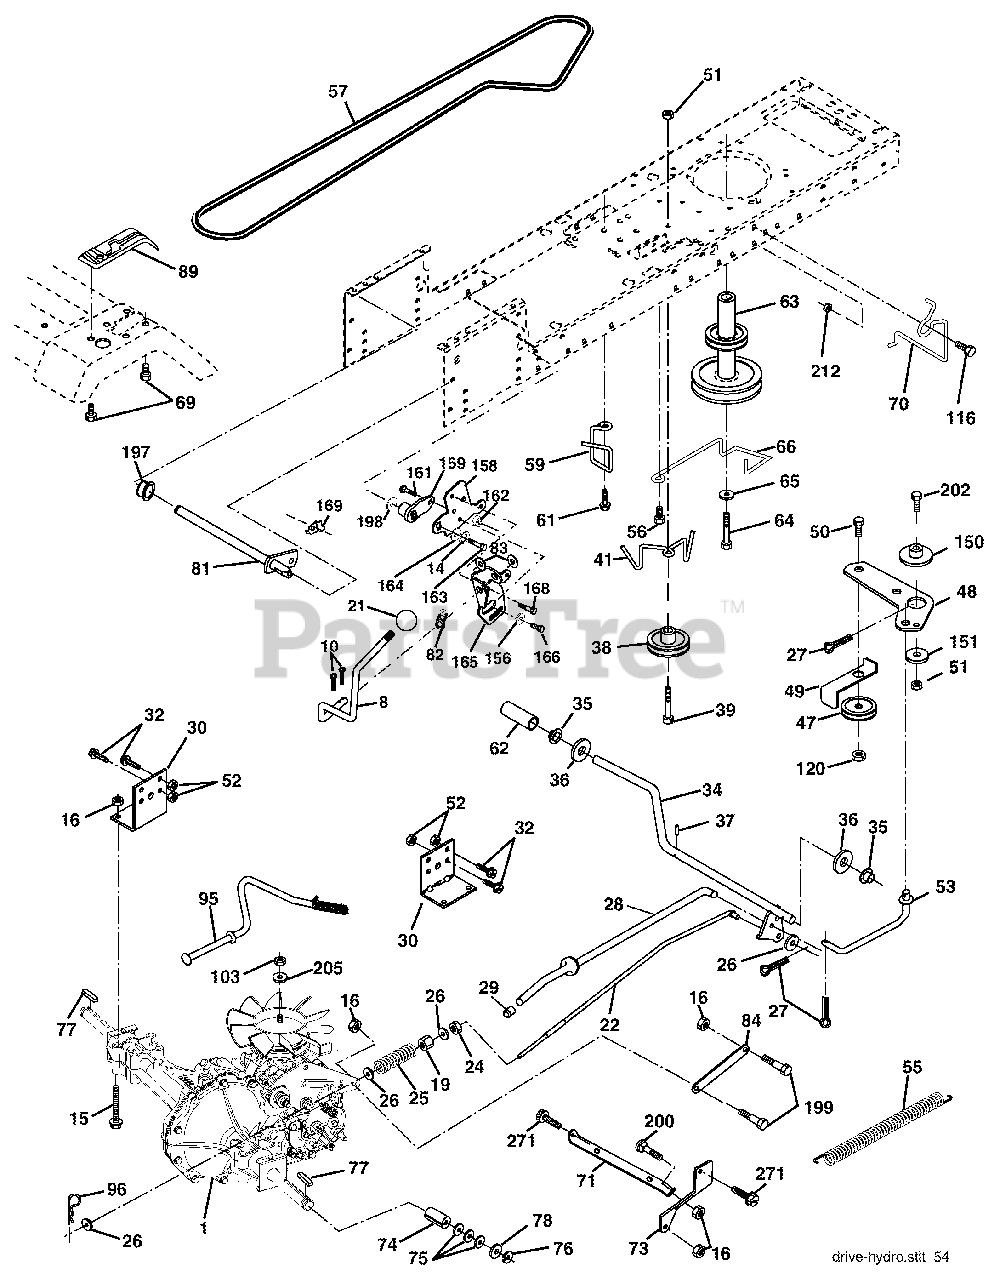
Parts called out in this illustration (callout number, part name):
10	Pin, Cotter 1/8 x 1
14	Washer Lock 1/4
15	Bolt Hex Flghd 5/16-18 Gr. 5
16	Nut, Lock Hex w/Ins 5/16-18 Unc
19	Nut, Lock Hex w/Wsh 3/8-16 Unc
21	Knob Rd. 1/2-13 Plstc. Thds. Blk.
22	Rod, Brake
24	Nut
25	Spring, Rod, Brake
26	Washer 13/32 x 13/16 x 16 Ga.
27	Pin, Cotter 1/8 x 3/4
28	Rod, Parking Brake
29	Cap, Parking Brake
30	Bracket, Transmission
32	Bolt Hex 5/16-18 Unc x 3/4
34	Shaft, Foot Pedal
35	Bearing, Nylon
36	Washer
37	Pin, Roll
38	Pulley, Idler, Composite
39	Bolt
41	Keeper, Belt, Idler
47	Pulley, Idler, V-Belt
48	Bellcrank Clutch Grnd Drustl
49	Retainer, Belt
50	Bolt 3/8-16 x 1-1/2 Gr. 5
51	Nut
52	Nut Crownlock 5/16-28
53	Link, Clutch
55	Spring, Return, Clutch
56	Screw 3/8-16 x 1-1/4
57	V-Belt, Drive
59	Keeper, Belt, Center
61	Screw, 3/8-16 x .875
62	Cover, Pedal
63	Pulley, Engine
64	Bolt Hex 7/16-20 x 4
65	Washer
66	Keeper, Belt Engine Hydro
69	Screw Hex Wsh Hi-Lo 1/4-1/2 Unc
70	Guide, Belt, Mower Drive RH
71	Strap, Torque, Lh
73	Strap, Torque, Rh
74	Spacer, Axle
75	Washer 25/32 x 1-1/4 x 16 Ga.
76	Ring, E
77	Key, Square
78	Washer 25/32 x 1-5/8 x 16 Ga.
81	Shaft Asm Cross
82	Spring, Torsion
83	Washer 17/32 x 3/4 x 16 Ga.
84	Link Transaxle
89	Console, Shift
95	Control Asm Bypass Hydro
96	Spring, Retainer 1"
103	Nut, Hex Jam Toplock 1/2-20 Unf
116	Bolt 3/8-16 x 1
120	Bolt Hex 3/8-16 x 1-1/2
150	Spacer Retainer
151	Washer 13/32 x 2 x 10
156	Washer 5/16 x 1.0 x 1.25
158	Bracket Shift Mount
159	Hub Shift
161	Bolt Rdhd Sqnk 1/4-20 x 3/4 Gr. 5
162	Nut Crownlock 1/4-20 Unc
163	Bolt Hex Fin 1/4-20 x 1
164	Washer 5/8 x .281 x 10 Ga.
165	Bracket Pivot Lever
166	Screw 5/16 x 1.0 x .125
168	Bolt Shoulder 5/16-18 x .561
169	Plate Fastening LT
197	Nyliner Snap-in 5/8" ID
198	Washer Nyl 7/8 ID x .105" HYD
199	Bolt Shoulder 5/16-18 Unc
200	Bolt Rdhd Sqnk 5/16-18 Unc x 1
202	Bolt Car SH 3/8-16 x 1-1/2 Gr 5
205	Washer 17/32 x 1 x 16 Ga
212	Nut Hex Flange Lock
258	Screw 3/8-16 x 3/4
